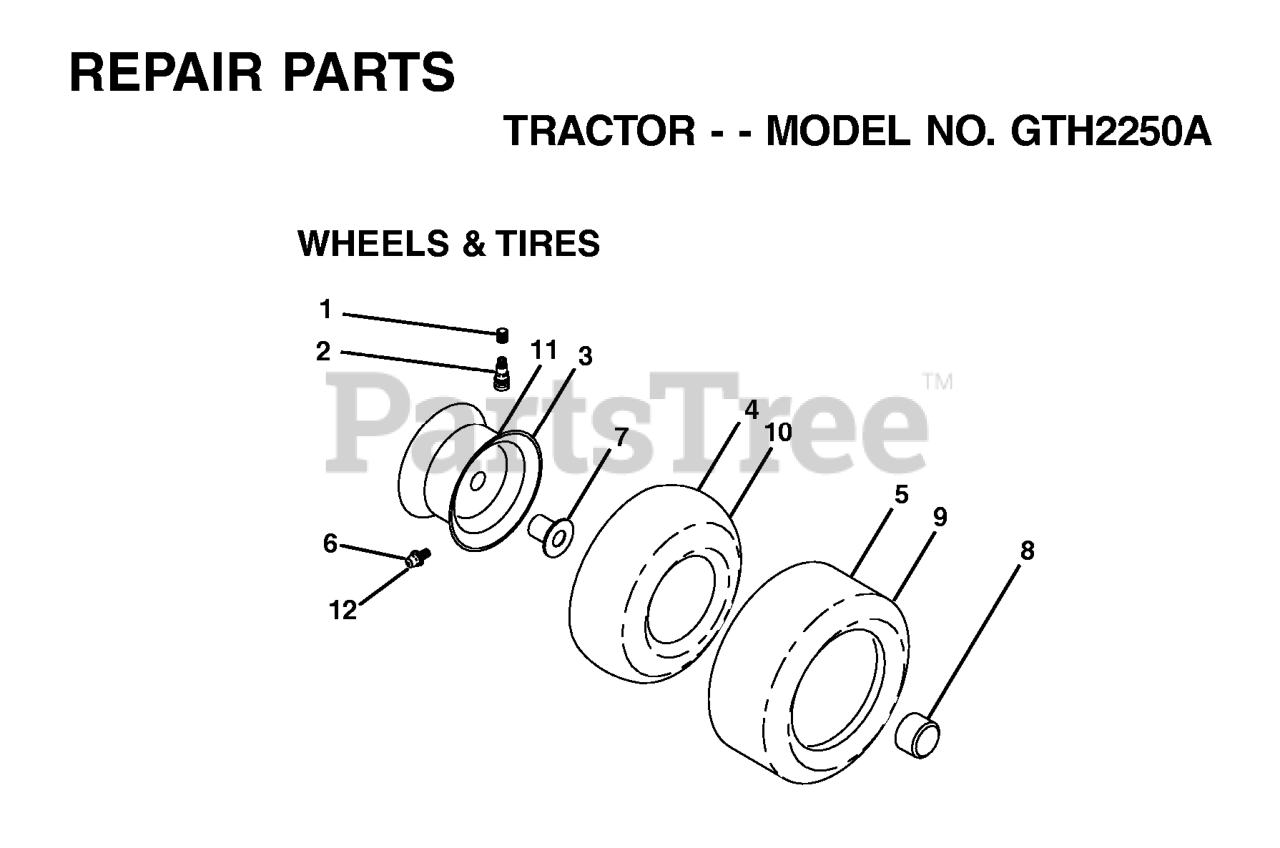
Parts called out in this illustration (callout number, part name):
2	VALVE STEM LT
3	RIM ASSEMBLY, FRONT
4	TUBE.16X6.5/7.5-8
5	TIRE HEAVY DUTY
6	FITTING LT
7	BEARING T
8	CAP, AXLE BLK
9	TIRE HEAVY DUTY
10	TUBE.23X9.5-12
11	RIM.ASM.12X7.REAR.SILVER
12	ZERK FITTING M
